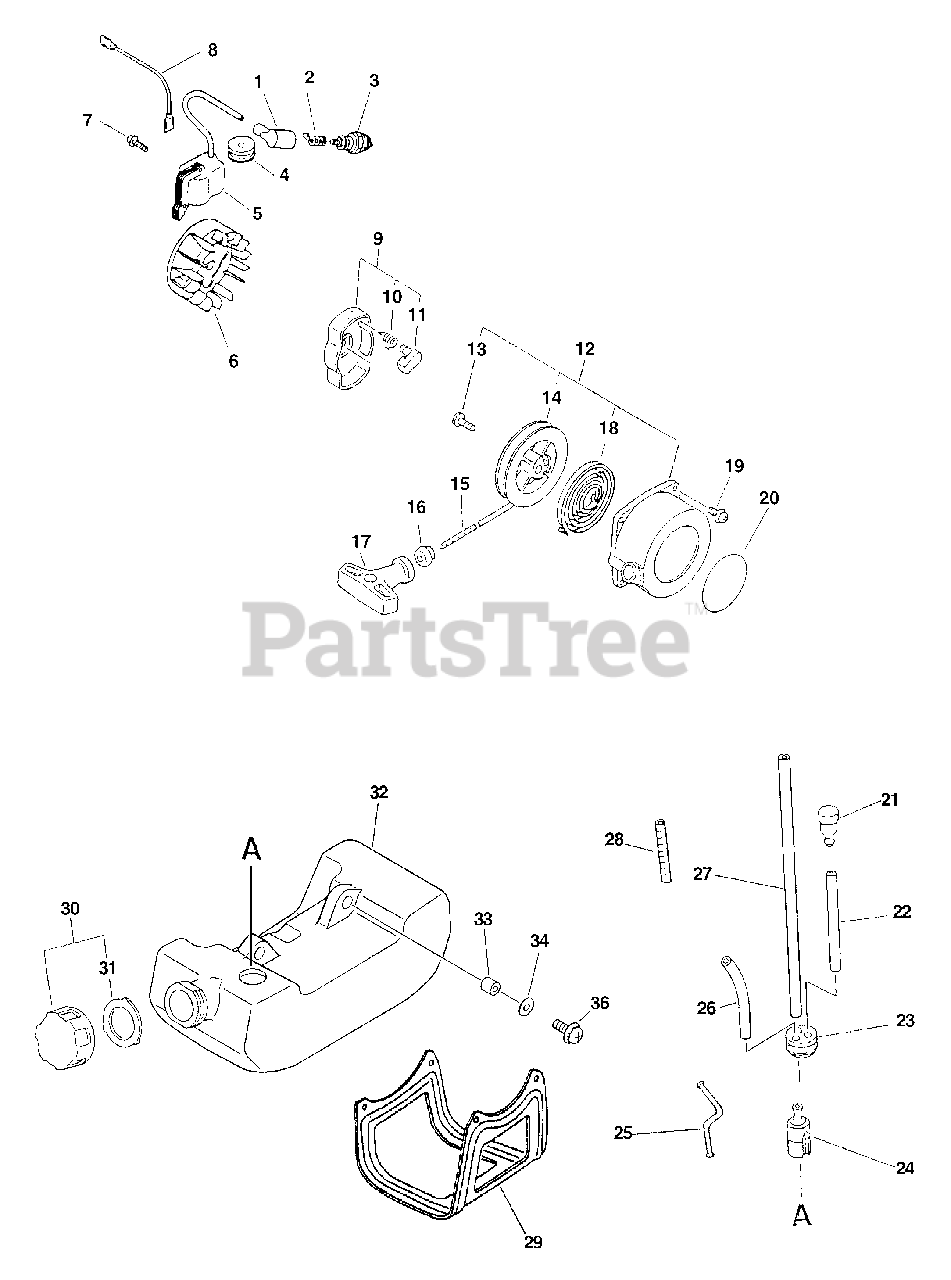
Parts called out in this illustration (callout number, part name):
1	CAP, SPARK PLUG
2	TERMINAL, SPARK PLUG CAP
3	SPARK PLUG -- BPM-7Y
3	SPARK PLUG -- BPMR-7A
5	COIL, IGNITION
6	FLYWHEEL
7	SCREW - 4X22
8	LEAD - IGNITION
9	STARTER PAWL ASSY
10	SPRING, RETURN
11	PAWL, STARTER - BLACK
12	STARTER ASSY
14	REEL, ROPE
15	ROPE, STARTER - 3X1000
16	GUIDE, ROPE
17	GRIP, STARTER
18	SPRING, REWIND
19	SCREW - 4X16
20	LABEL - ECHO
21	VENT, FUEL TANK
22	PIPE - 3X5X70 -- BLACK
23	GROMMET
24	FILTER, FUEL
25	CONNECTOR, PIPE
26	PIPE - 3X6X90 -- CLEAR
27	PIPE - 3X5X180 -- BLACK
28	PIPE, FUEL - CORRUGATED
29	GUARD, FUEL TANK
30	CAP ASSY
31	GASKET, CAP
32	FUEL TANK ASSY
34	WASHER - 5
35	SCREW - 5X16
